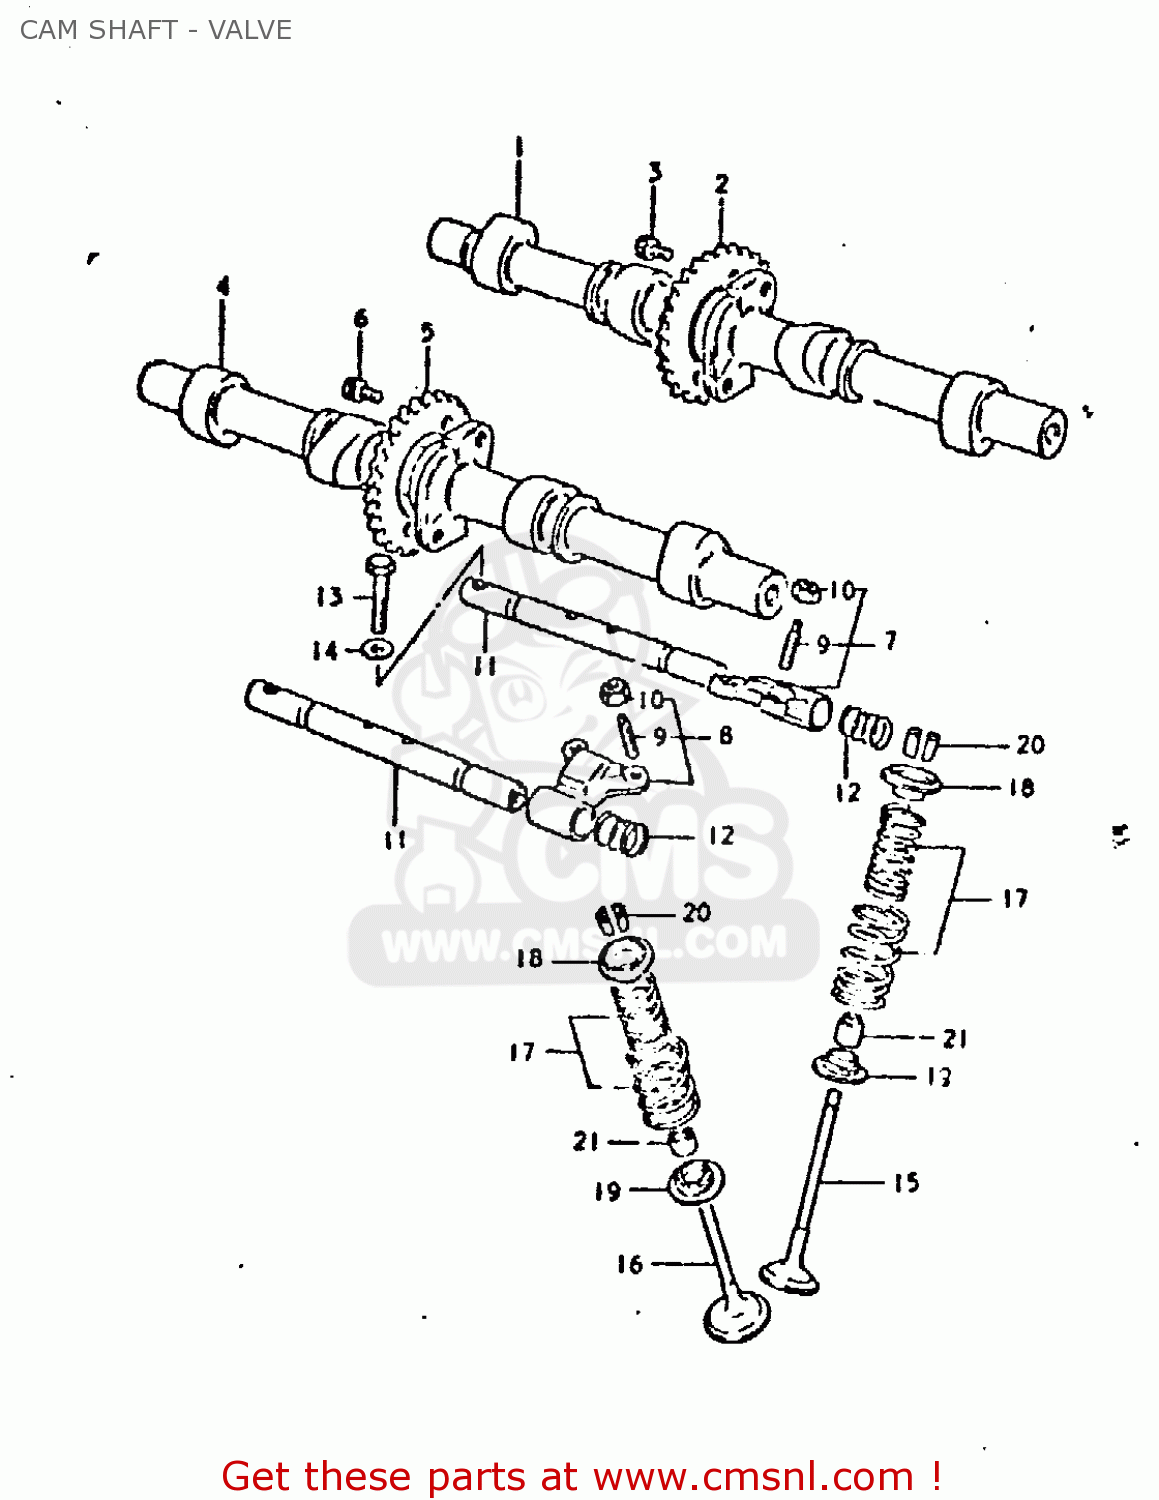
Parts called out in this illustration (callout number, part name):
1	CAMSHAFT
2	SPROCKET,CAMSHAFT
3	BOLT 6X11
4	CAMSHAFT,EXHAUST
5	SPROCKET,EXHAUST CAMSHAFT
6	BOLT 6X11
7	ARM,VALVE ROCKER
8	ARM,VALVE ROCKER
9	SCREW,TAPPET ADJUSTING
10	NUT,ADJUSTING
11	SHAFT,VALVE ROCKER
12	SPRING
13	BOLT
14	WASHER
15	VALVE,INTAKE
16	VALVE,EXHAUST
17	SHIM,TAPPET
18	RETAINER,VALVE SPRING
19	SEAT,VALVE SPRING
20	COTTER VALVE
21	OIL SEAL
